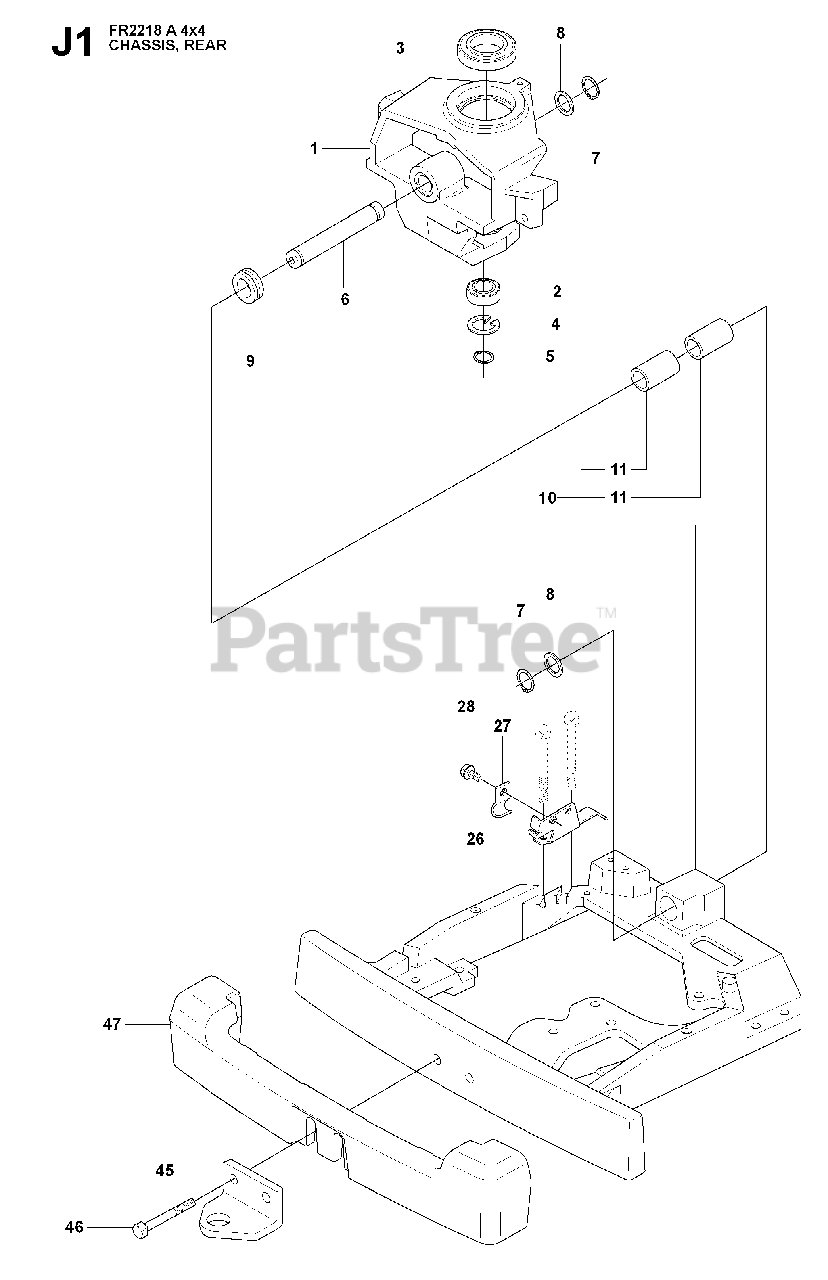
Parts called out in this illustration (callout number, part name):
2	BALL BEARING 6005-2RS
3	BALL BEARING 6010 2RS1
4	CIRCLIP SGH 47
5	RETAINING RING SGA 25
7	RETAINING RING SGA 25
45	DRAW RING
